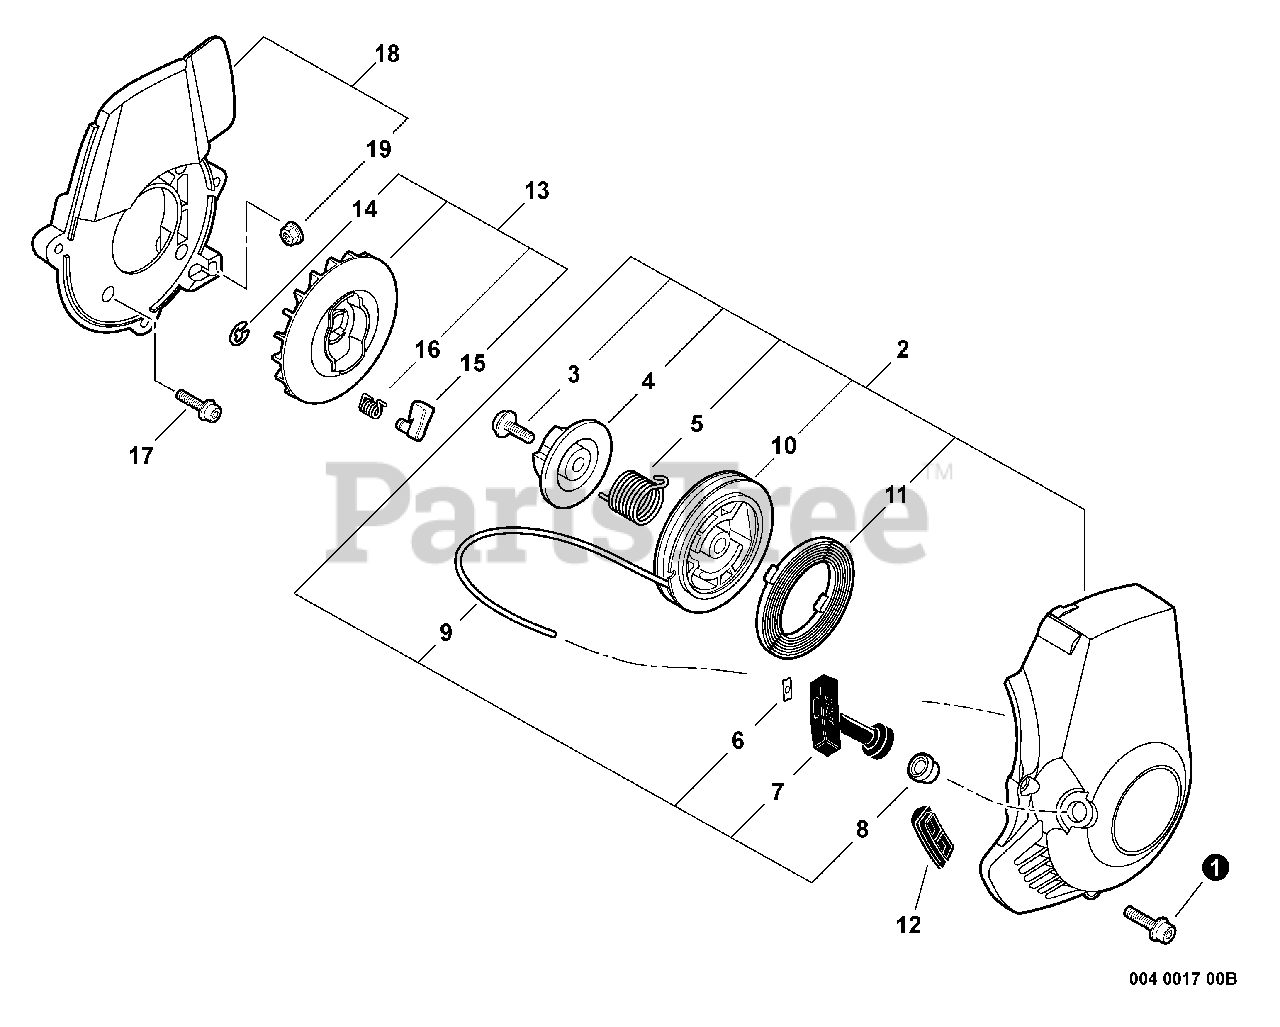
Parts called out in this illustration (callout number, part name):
1	BOLT 5×14
2	STARTER, RECOIL
3	SCREW
4	PLATE, CAM (NLA SEE PB 15-06)
5	SPRING, TORSION
6	RETAINER, ROPE
7	GRIP, STARTER
8	GUIDE, ROPE
9	ROPE, STARTER 3×700
10	REEL, ROPE
11	SPRING, RECOIL
12	CUSHION
13	PAWL ASSY, STARTER
14	E-RING 4
15	PAWL, STARTER
16	SPRING, RETURN
17	BOLT 4×16
18	SPACER ASSY.
19	NUT, FLANGE M5
